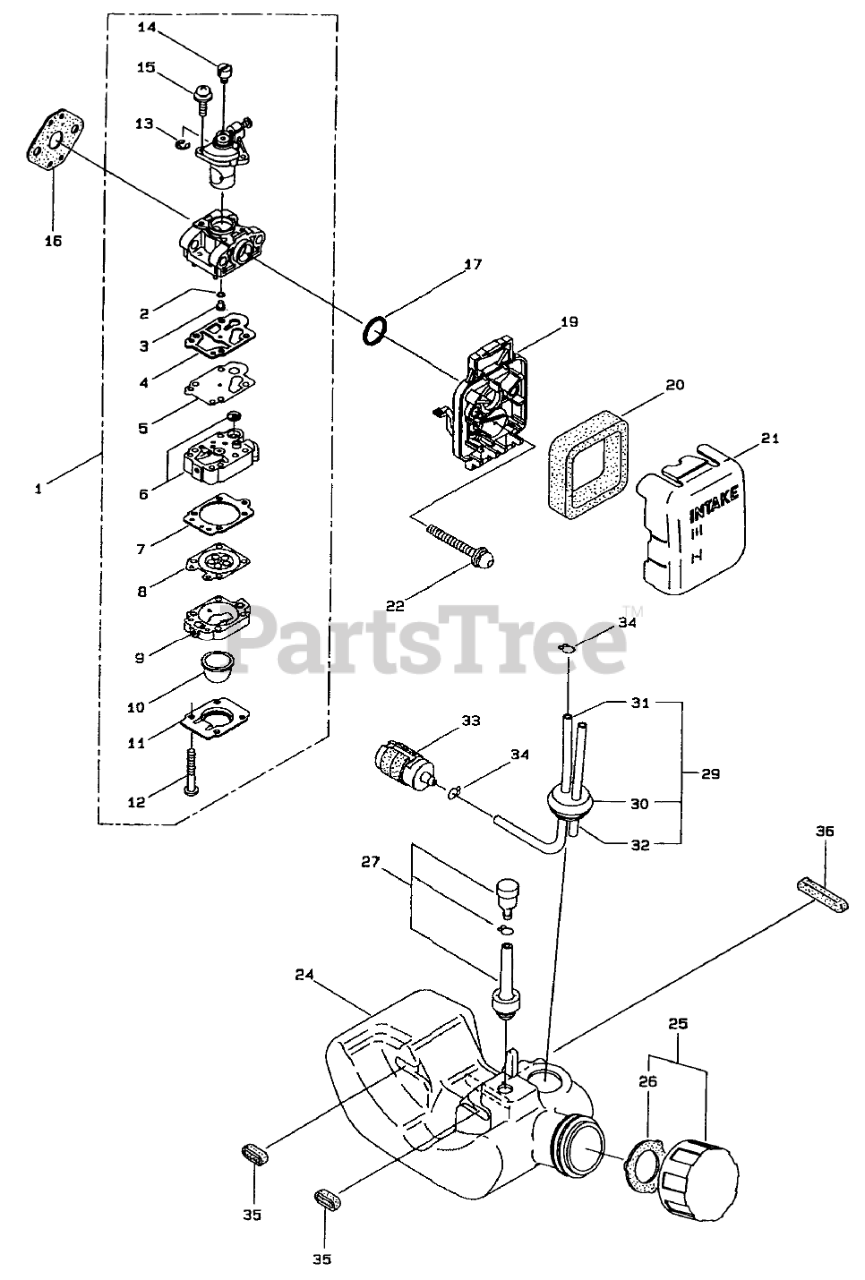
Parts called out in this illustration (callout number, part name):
1	Carburetor Assembly (Incl. Ref. # 2-15)
2	O-RING
3	JET - MAIN
4	GASKET (NC)
5	PUMP - DIAPHRAGM (NC)
6	PUMP - BODY (NC)
7	GASKET (NC)
8	ASM - DIAPHRAGM
9	PURGE - BODY (NC)
10	PRIMER
11	PLATE - COVER (NC)
12	SCREW (NC)
13	E-RING
14	SWIVEL
15	SCREW
16	GASKET
17	O-RING
19	HOUSING - AIR CLEANER
20	ELEMENT
21	COVER
22	CAPSCREW
24	TANK - FUEL
25	Fuel Tank Cap Assembly (Incl. Ref. # 26)
26	PACKING
27	ASM - BREATHER
29	Fuel Pipe Assembly (Incl. Ref. # 30-32)
30	GROMMET
31	PIPE - FUEL
32	PIPE - RETURN
33	ASM - FUEL FILTER
